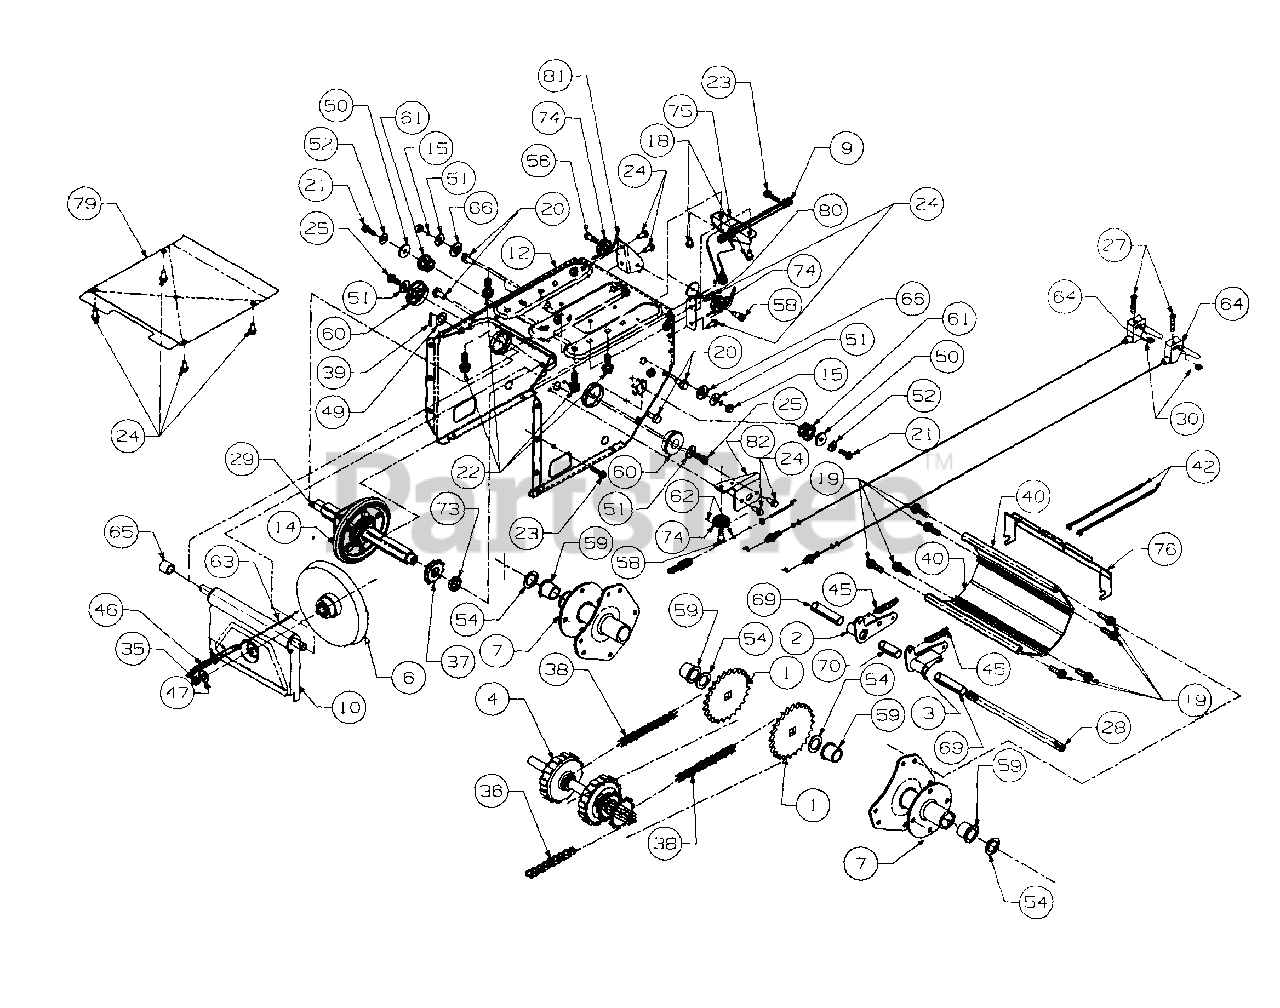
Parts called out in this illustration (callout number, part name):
1	Axle Assembly
2	Dog Assembly - R.H.
3	Dog Assembly - L.H.
4	Shaft Assembly
6	Disc Assembly
14	Wheel Assembly Friction
15	Screw
18	Screw
19	Screw
20	Screw
21	Screw
23	Screw
24	Screw
25	Screw
27	Screw
28	Shaft
29	Shaft
30	Nut Flange
35	Nut Jam
36	Chain
37	Sprocket
38	Chain
39	Pin Cotter
40	Housing Track
42	Cable Tie
45	Spring
46	Spring
47	Washer-Bell
49	Washer-Flat
50	Washer-Flat
51	Washer-Bell
52	Washer-Bell
54	Washer-Flat
56	Lubricant
58	Screw-Shoulder
59	Bearing-Flange
60	Bearing-Ball
61	Bearing-Hex Flange
62	Cable-Auger Clutch
63	Cable-Drive Clutch
64	Cable with Trigger Lever
65	Spacer
66	Spacer-Shoulder
69	Spacer-Split
70	Spacer-Split
73	Spacer
74	Roller-Cable
